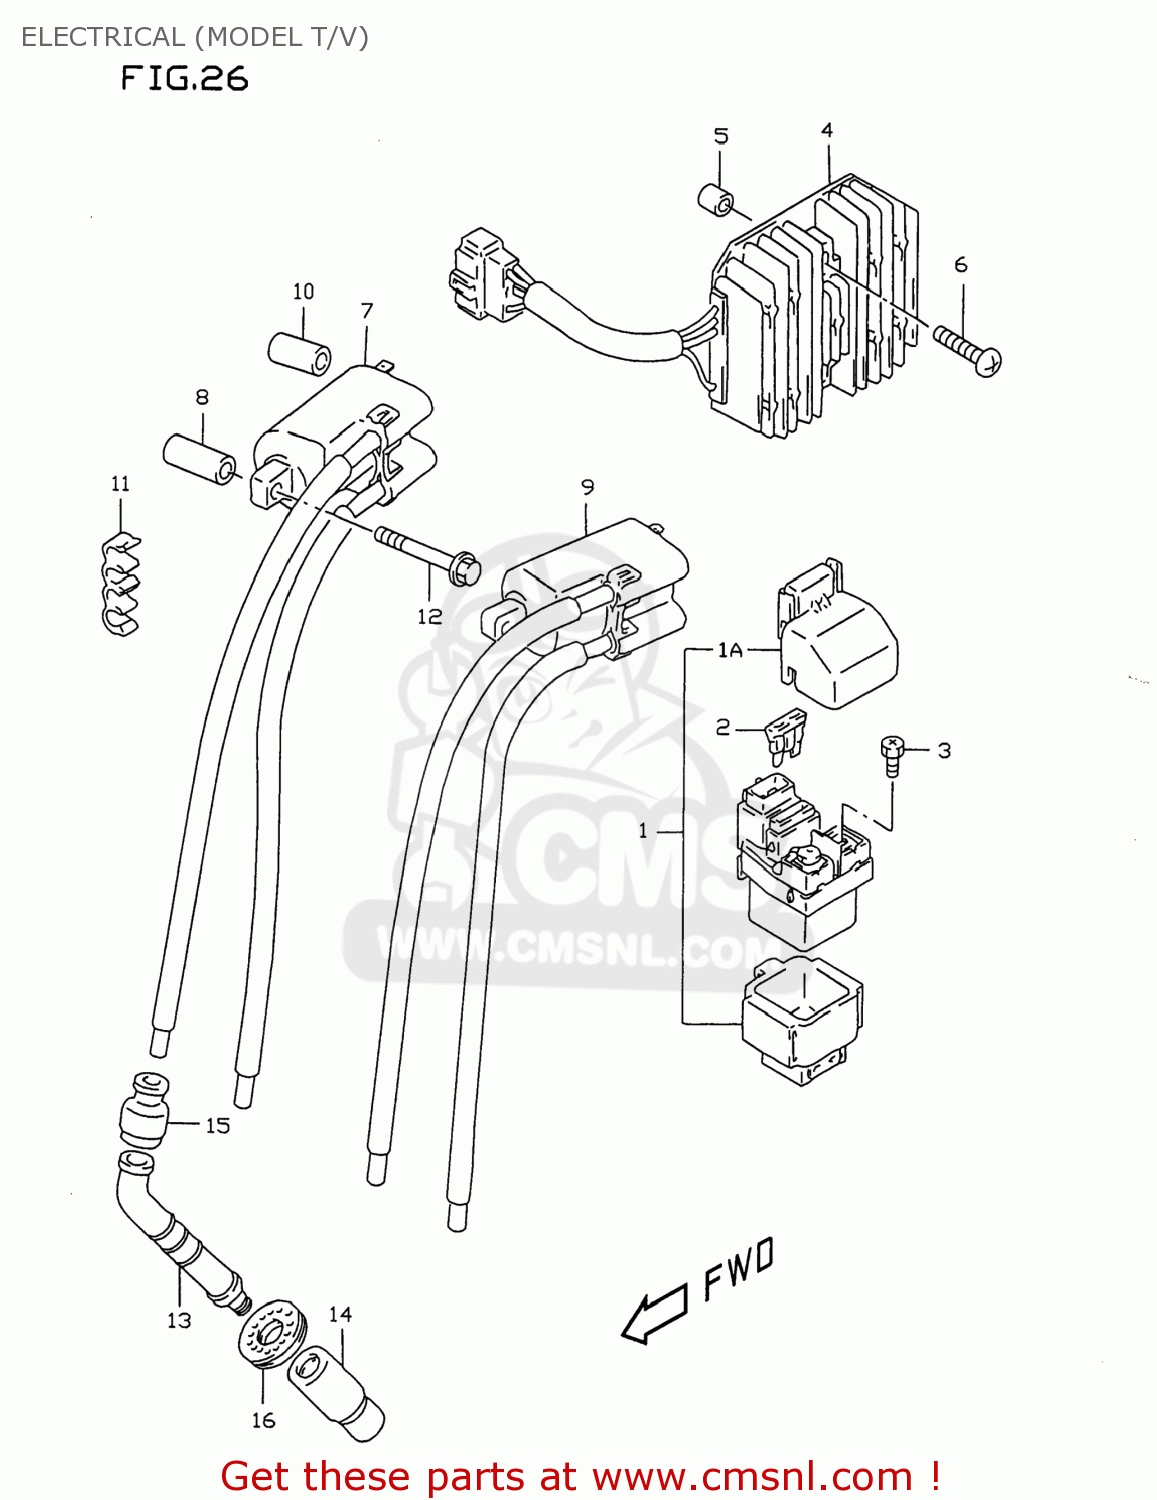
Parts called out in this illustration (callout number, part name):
1	RELAY ASSY,STARTING MOTOR
1A	COVER,STARTER RELAY
2	FUSE(30A)
3	SCREW(6X8)
4	RECTIFIER ASSEMBLY
5	SPACER
6	SCREW
7	COIL ASSY,IGNITION
8	SPACER(6.5X10.5X25)
9	COIL ASSY,IGNITION
10	SPACER(6.4X10X28)
11	CLIP
12	BOLT
13	CAP ASSY,SPARK PLUG
14	SEAL,SPARK PLUG
15	SEAL,HIGH TENSION CORD
16	COVER,SPARK PLUG CAP
